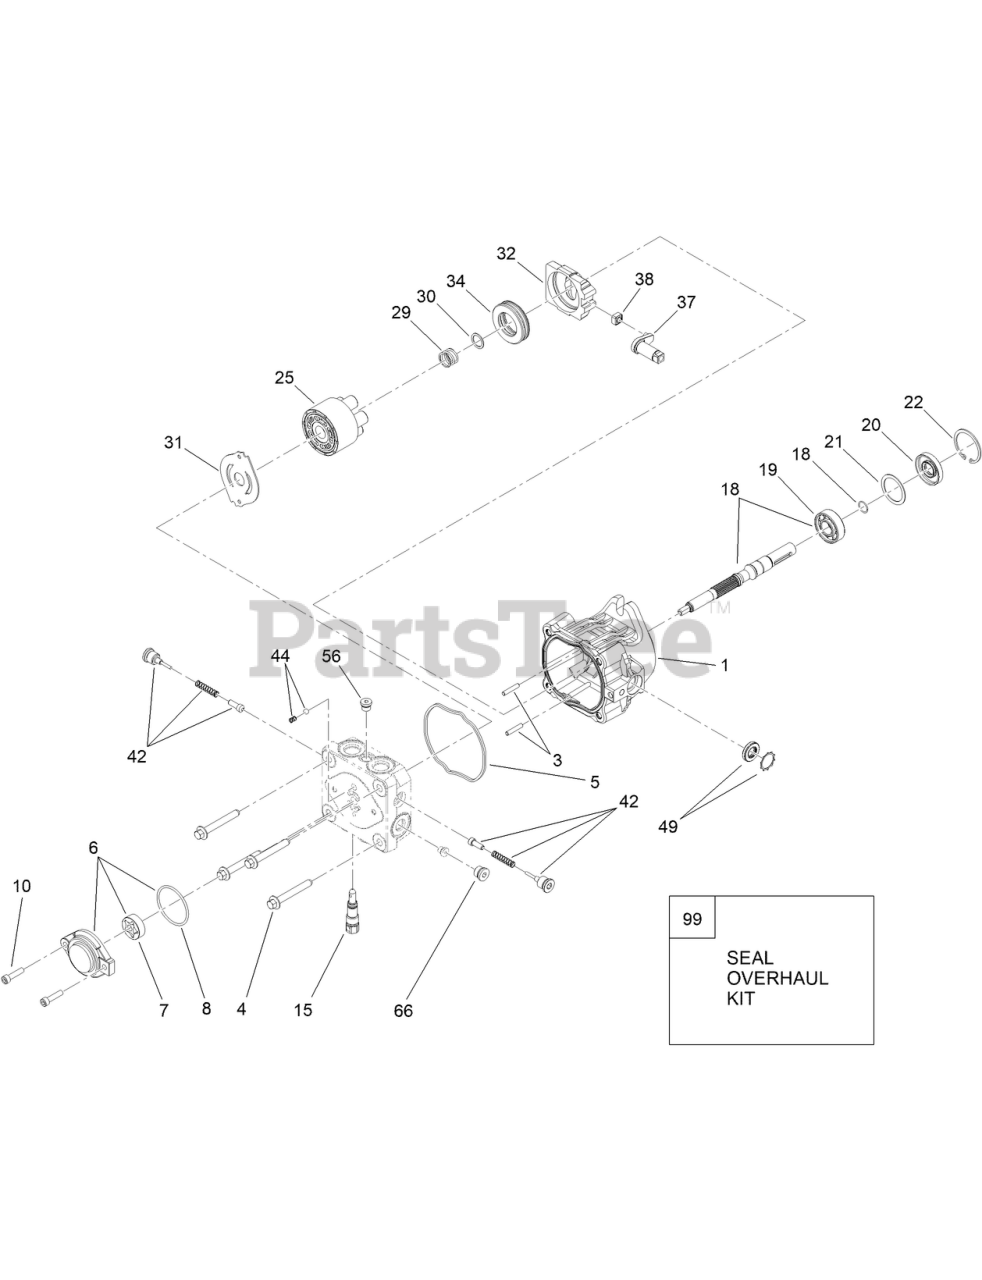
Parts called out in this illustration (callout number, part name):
1	HOUSING KIT
3	PIN-HEADLESS, STRAIGHT
4	BOLT-HF
6	CHARGE PUMP KIT
7	GEROTOR ASM
8	O-RING
10	CAPSCREW
15	BYPASS VALVE KIT
18	INPUT SHAFT KIT
19	BEARING-BALL
20	SEAL-LIP
21	SPACER
22	RING-RETAINING
25	CYLINDER BLOCK KIT
29	SPRING-BLOCK
30	WASHER-THRUST
31	PLATE-VALVE
32	SWASHPLATE-VARIABLE
34	BEARING-THRUST
37	ARM-TRUNNION, TAPERED SQUARE
38	GUIDE-SLOT
42	VALVE-CHECK (W/POPPET)
44	CHARGE RELIEF VALVE KIT
49	TRUNNION SEAL KIT
56	PLUG-HSH
66	PLUG-HSH
